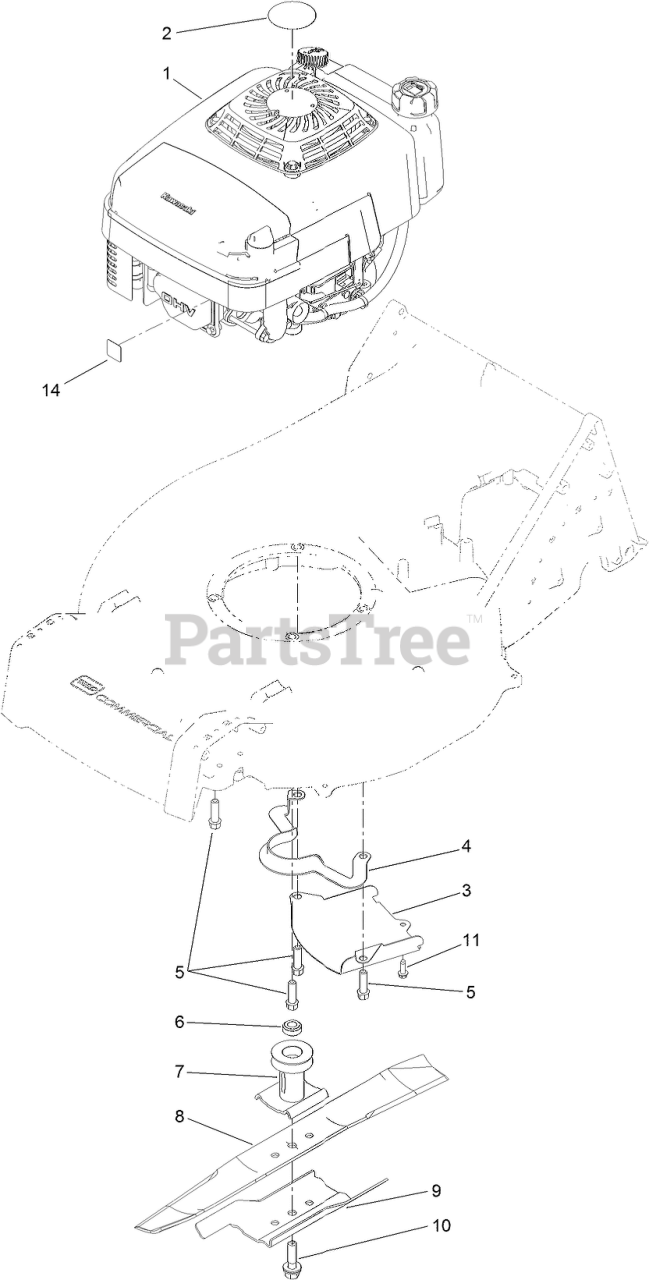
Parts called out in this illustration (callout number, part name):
1	ENGINE-KAWASAKI, FJ180V
3	SHIELD-GRASS
4	GUIDE-BELT
5	SCREW-TAPTITE
6	SPACER-DRIVER, BLADE
7	DRIVER-BLADE
8	BLADE-RECYCLING
9	ACCELERATOR-BLADE
10	BOLT-BLADE
11	SCREW-HWHTF
14	DECAL-PRIMER
